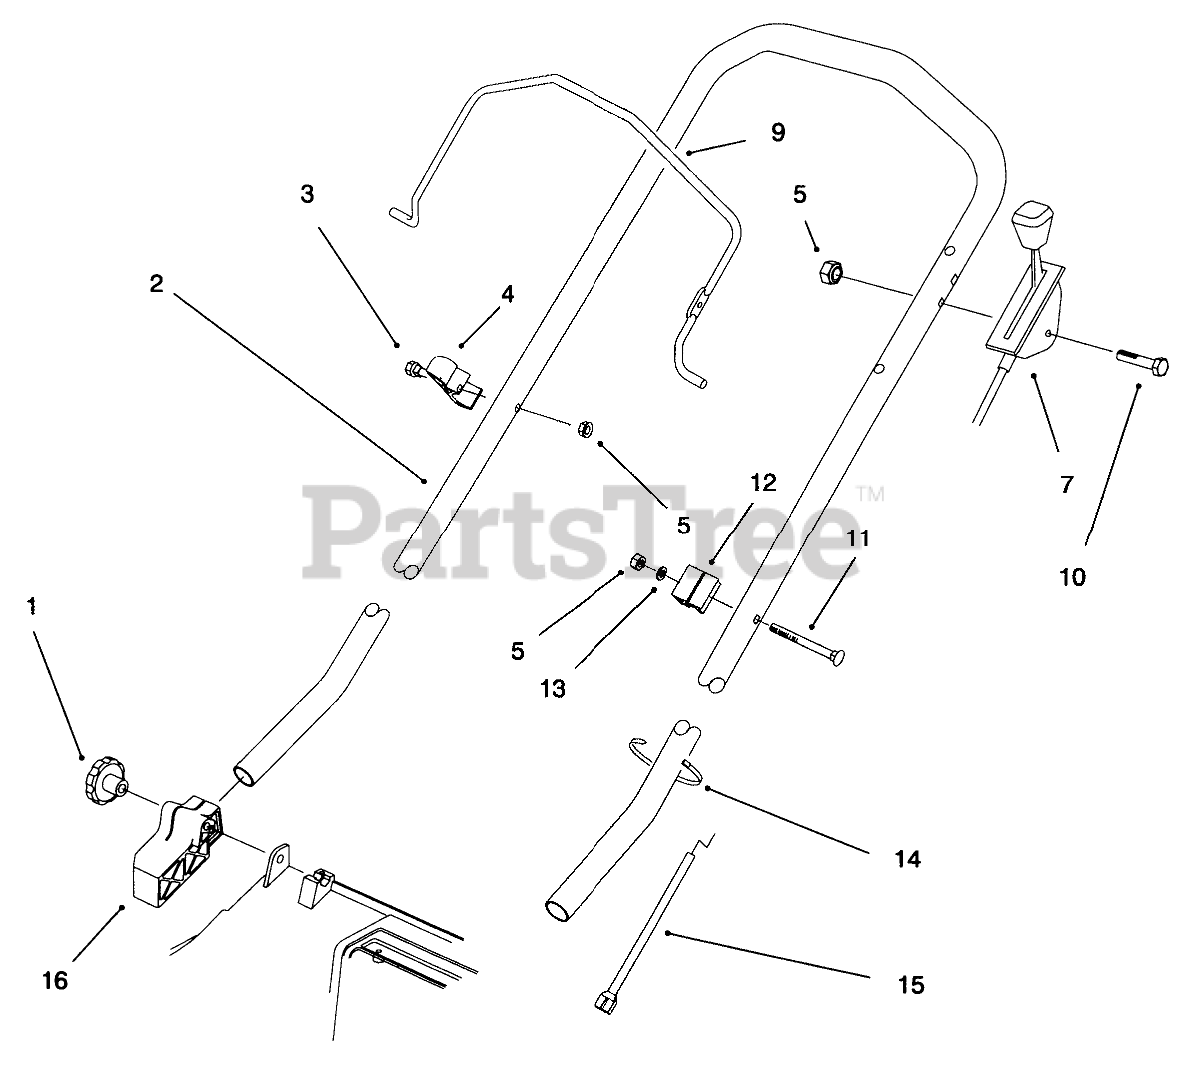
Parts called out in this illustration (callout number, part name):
2	HANDLE
3	.250-20X1.625 HH SCREW
4	GUIDE - ROPE
5	NUT-LOCK, NI
7	CONTROL - THROTTLE
9	Bail-Brake
10	SCREW-HH
11	SCREW-HANDLE
12	SUPPORT-CABLE
13	WASHER-FLAT
14	TIE-CABLE
15	CABLE - BRAKE
16	MOUNT-HANDLE, RH
